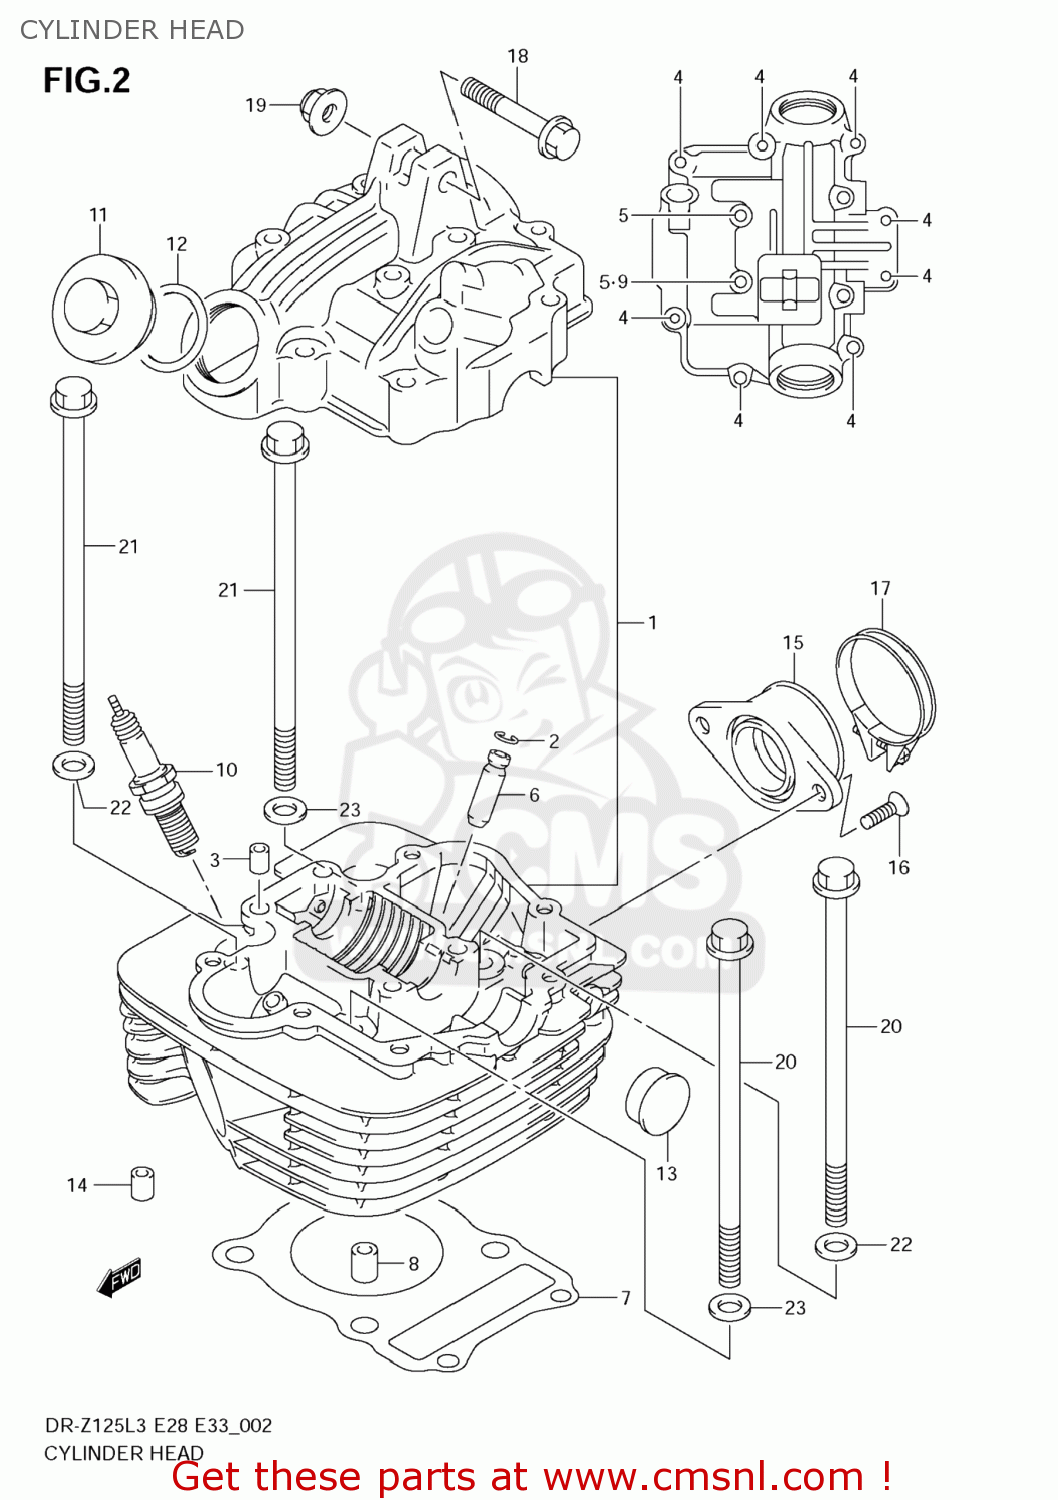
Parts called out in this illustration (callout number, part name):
1	HEAD ASSY,CYLINDER
2	RING,SNAP
3	PIN(6.2X8X11)
4	BOLT
5	BOLT
6	GUIDE,VALVE
7	GASKET.CYLINDER HEAD (NAS)
8	PIN
9	GASKET(5.8X13X1.2) (NAS)
10	PLUG,SPARK(DR8EA)
11	CAP,INSPECTION
12	O RING(D:3,ID:29.5)
13	PLUG(OD:22.5)
14	PAD,CYLINDER HEAD
15	PIPE ASSY,INTAKE
16	SCREW
17	CLAMP
18	BOLT(8X50)
19	NUT
20	BOLT(8X155)
21	BOLT(8X165)
22	WASHER(8.5X19X2.3)
23	GASKET(8.5X17X2.3) (NAS)
